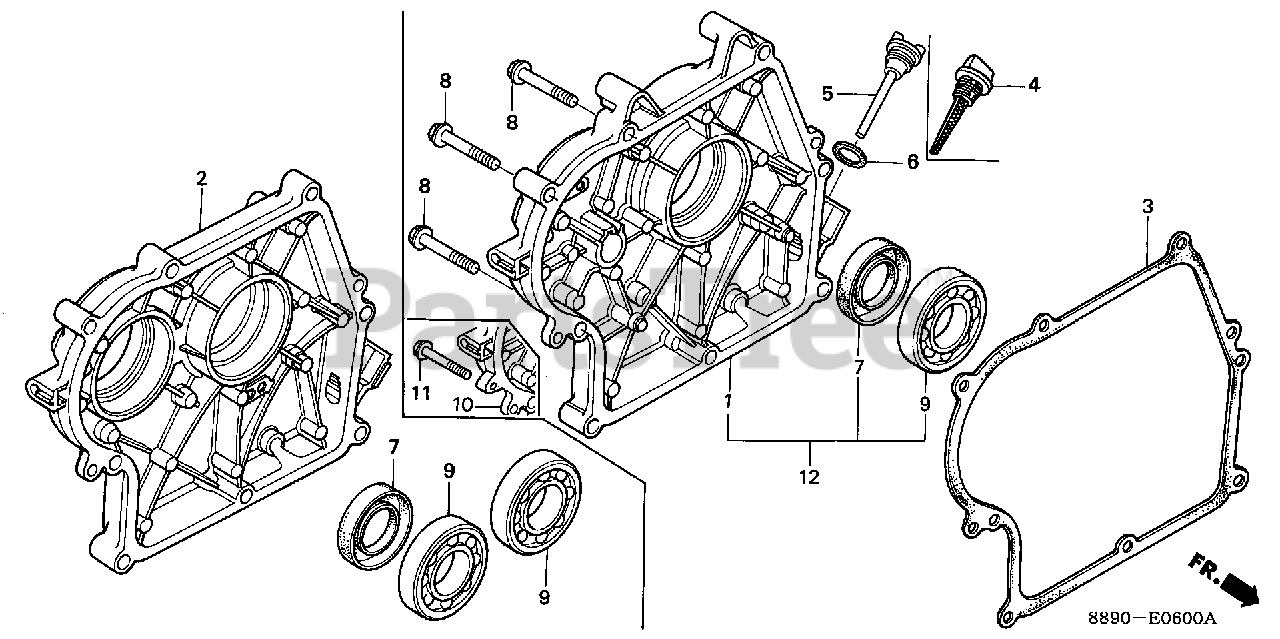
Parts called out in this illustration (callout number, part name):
1	COVER, CRANKCASE
3	GASKET, CASE COVER
5	CAP, OIL FILLER (YELLOW)
6	GASKET, OIL FILLER CAP
7	OIL SEAL (30X46X8)
8	BOLT, FLANGE (8X40)
9	BEARING, RADIAL BALL (6206)
